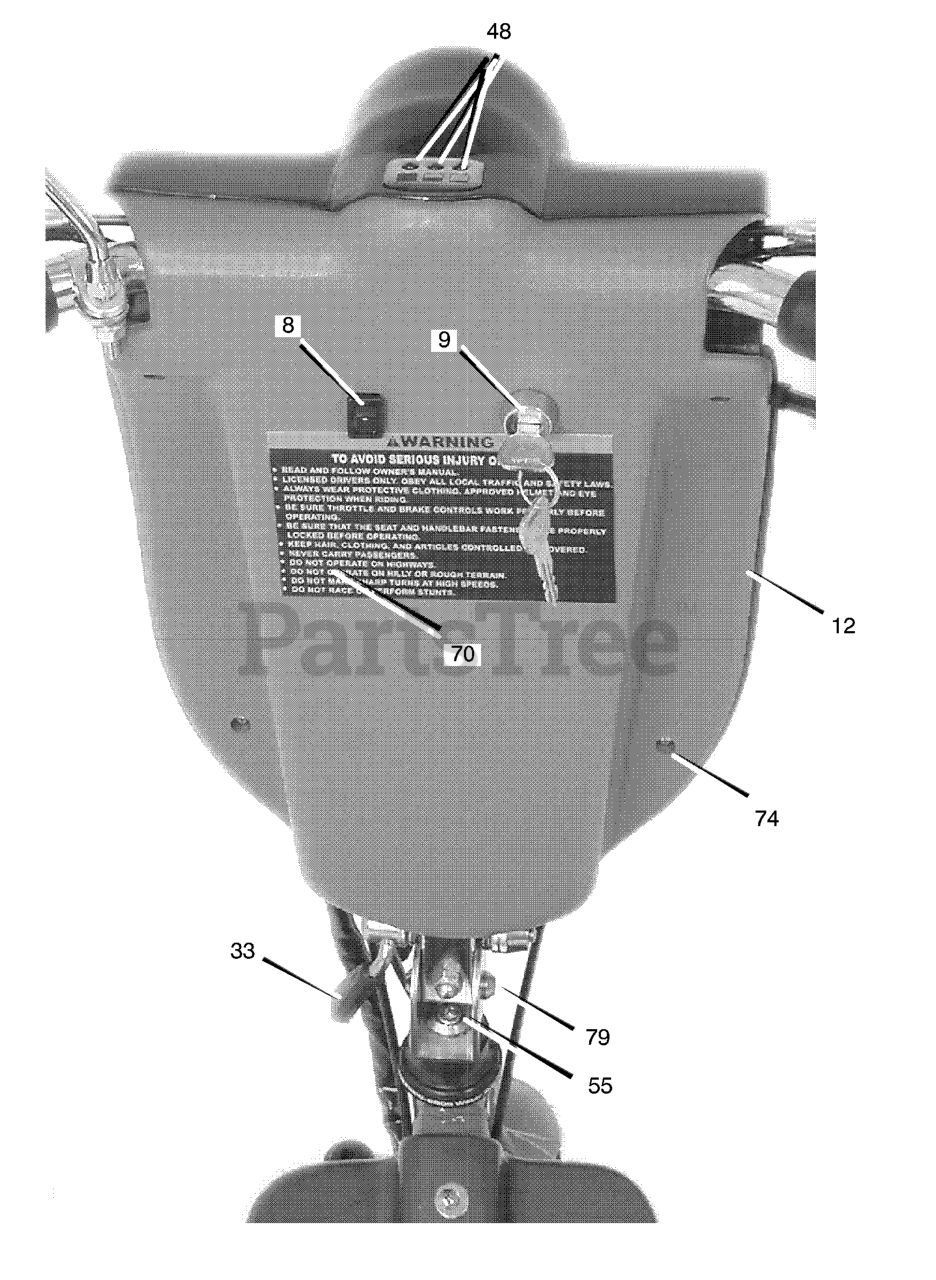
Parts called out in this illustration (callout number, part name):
8	Switch, Headlight
9	Switch, Ignition w/Key
12	Cover, Back Handlebar
33	Lever Assembly, Quick Release
48	Circuit Board, Battery Status Indicator Lights
55	Bolt Set, Expander
70	Label, Warning
74	Screw (4 required)
79	Screw, Pivot
